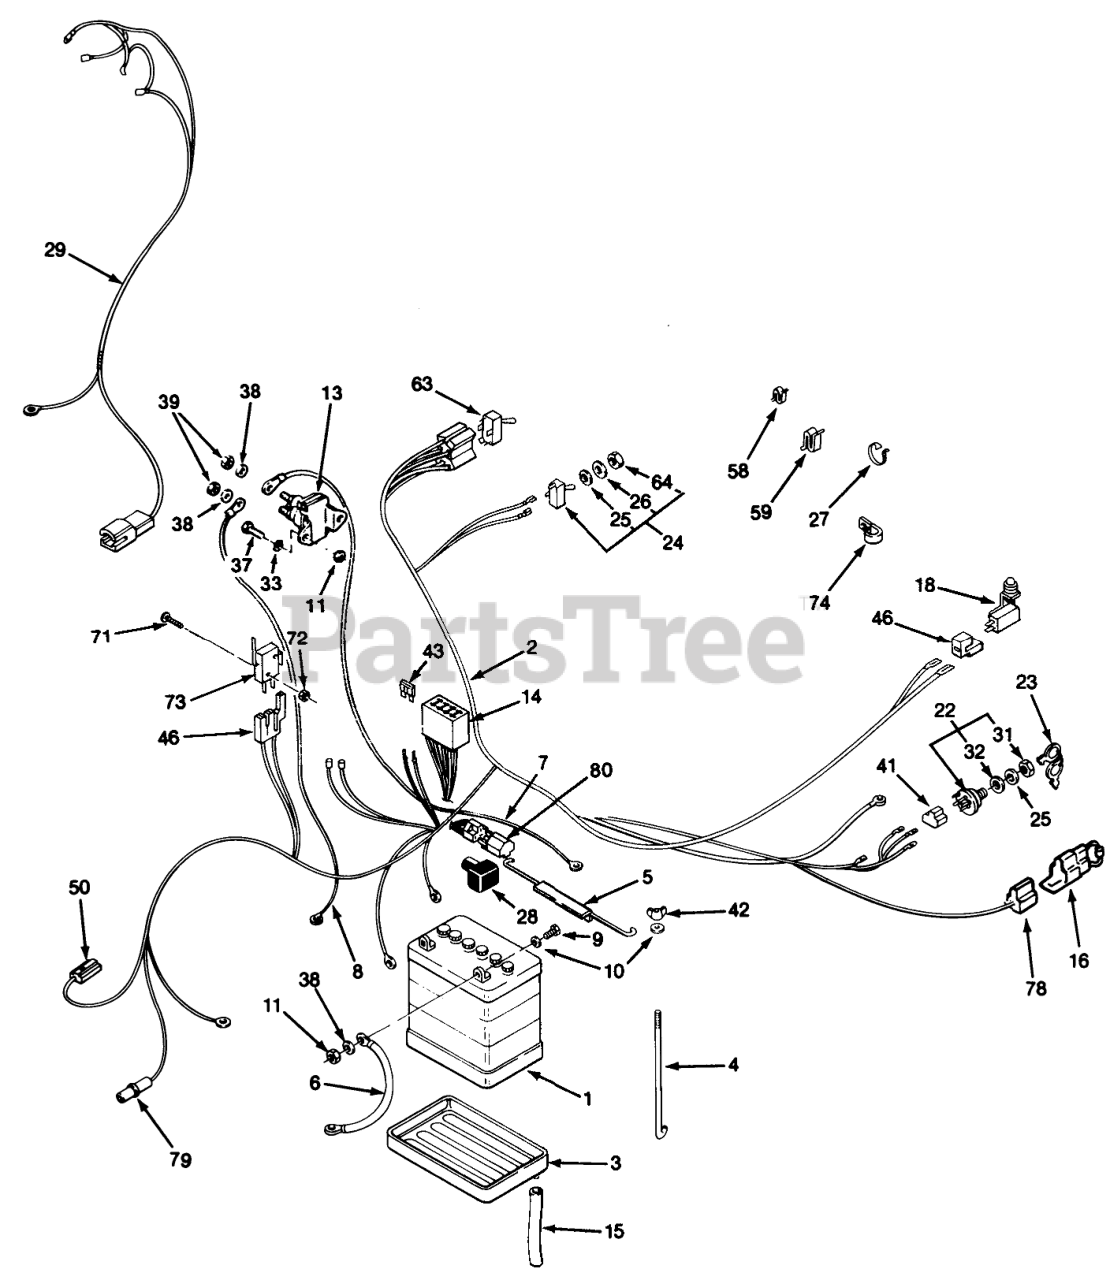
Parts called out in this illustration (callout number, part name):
1	Battery
2	Harness Wire (210-5 & 210-H)(Incl. Ref. #14, 41, 46, 78 & 79)
3	TRAY-BATTERY
5	ROD-BATTERY HOLD DWN
6	Cable-Battery
7	WIRE - 14" BLACK
8	ASSY WIRE
9	SCREW-HH
10	WASHER-FLAT
11	NUT-HEX
13	Solenoid (210-5 & 210-H)(Incl. Ref. #11)
14	FUSE-HOLDER 4 WAY
15	TUBE-BATTERY DRAIN
16	DIODE-ASS'Y
18	SWITCH-SEAT
22	Switch-Ignition (210-5 & 210-H)(Incl. Ref. #31-32)
23	Key
24	Switch-Light (212-5 & 212-H)(Incl. Ref. #25, 26 & 64)
25	Washer
26	Washer
27	PLASTIC TIE
28	Boot
29	HARNESS-HEADLIGHT
32	LOCKWASHER
33	WASHER-LOCK/EXT
37	Screw
38	WASHER-LOCK
39	NUT-JAM
41	CONNECTOR-5 WAY-SERV
42	NUT-WING
43	FUSE-BLADE, 15 AMP
46	CONNECTOR BODY
50	CONNECTOR BODY ELECT
58	CLIP
59	SPEED CLIP
63	PTO-SWITCH W/COVER
71	Screw
72	NUT HEX 4-40 ELAST
73	SWITCH - CLUTCH
74	CLAMP
78	CONNECTOR BODY B
79	SOCKET HOUSING
80	RELAY
